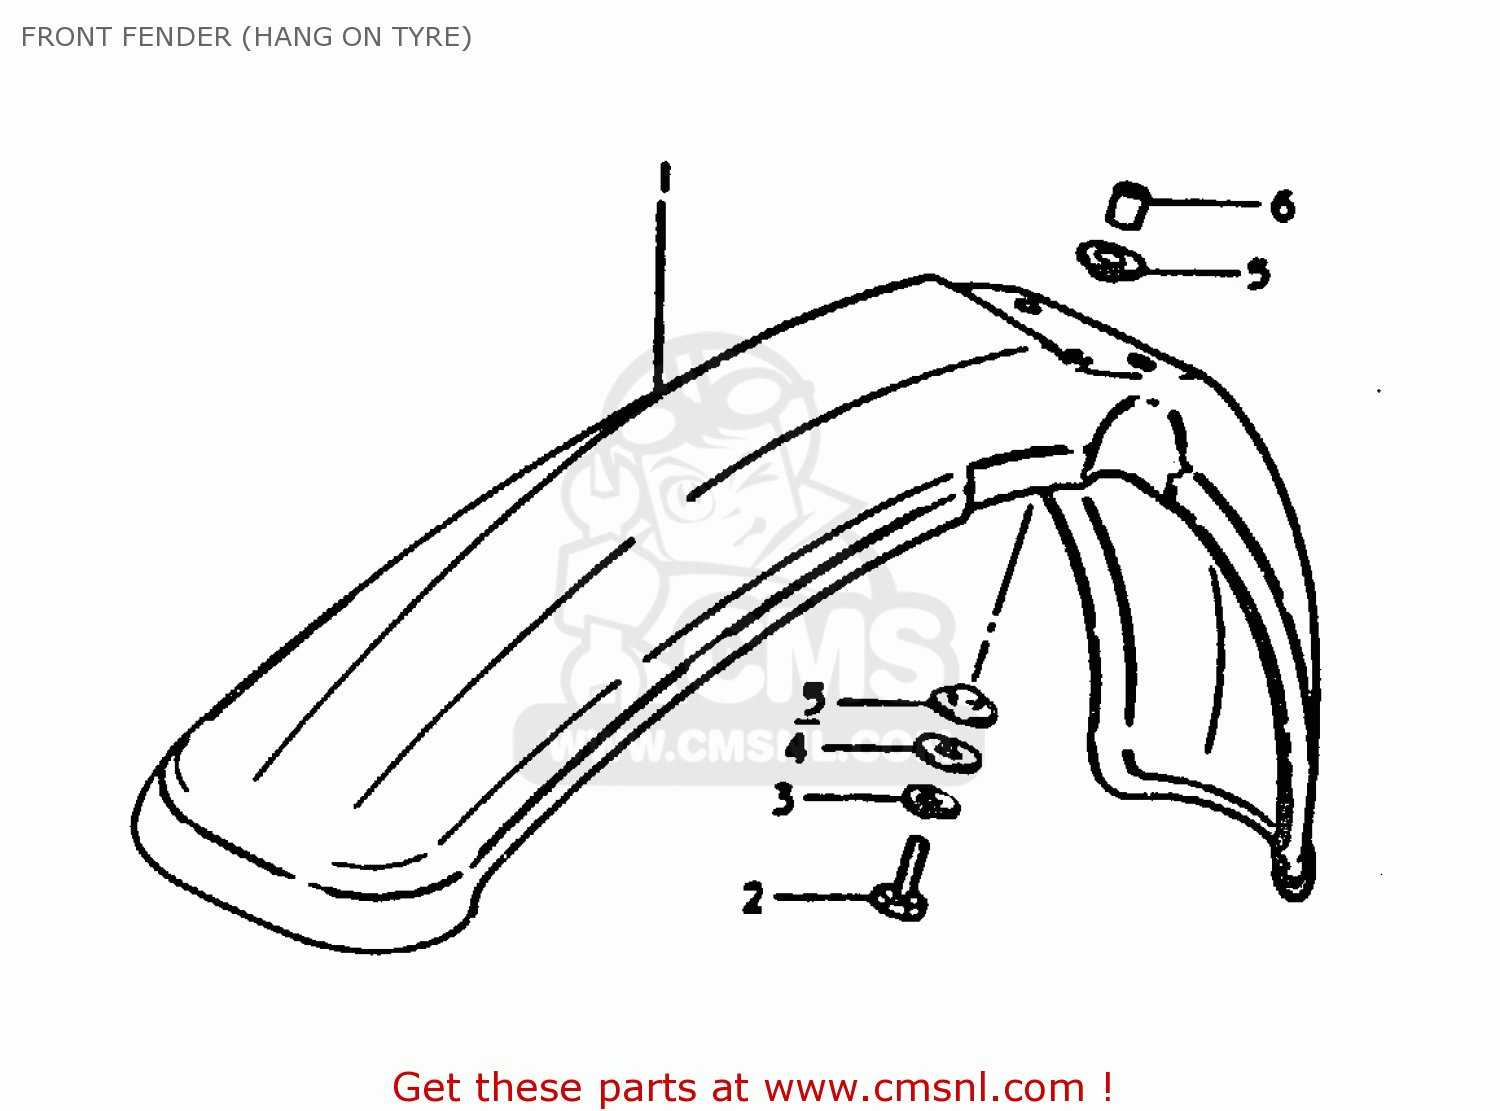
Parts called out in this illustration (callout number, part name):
1	FENDER,FR
2	BOLT
3	LOCK WASHER
4	WASHER
5	SPACER
6	SPACER (6.8X10X20)
